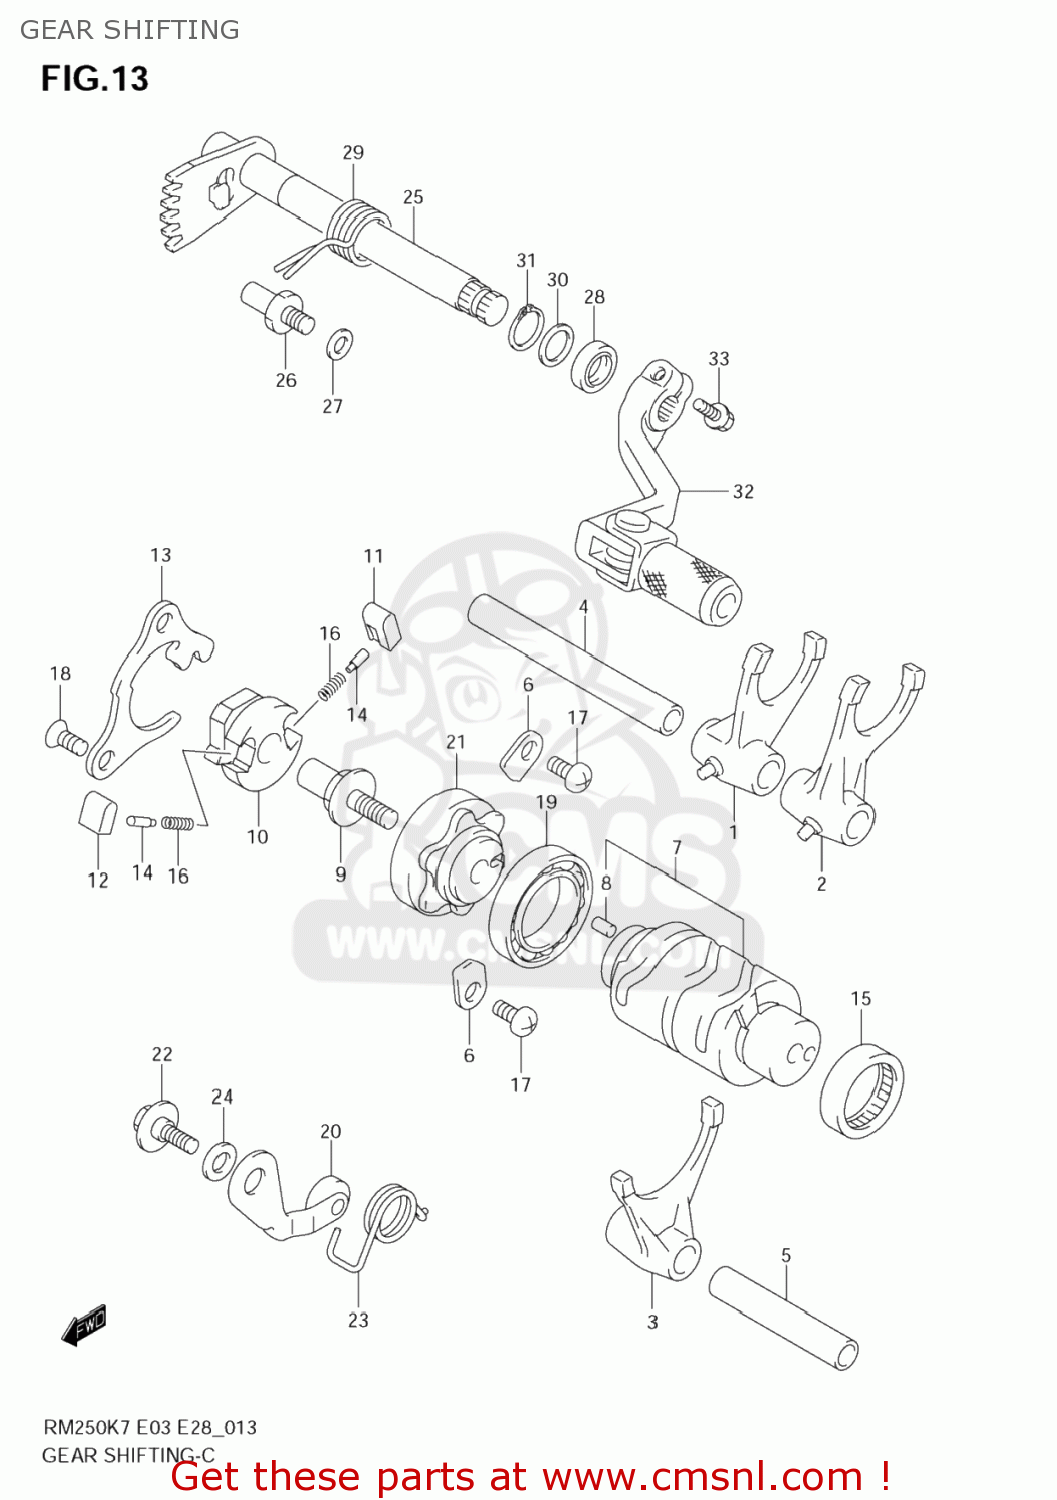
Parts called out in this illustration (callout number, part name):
1	FORK,GEAR SHIFT NO.1
2	FORK,GEAR SHIFT NO.2
3	FORK,GEAR SHIFT NO.3
4	SHAFT,GEAR SHIFT FORK(L:95)
5	SHAFT,GEAR SHIFT FORK(L:60)
6	RETAINER
7	CAM,GEAR SHIFT
8	PIN
9	PIN,GEAR SHIFT CAM
10	GEAR,GEAR SHIFT CAM DRIVEN
11	PAWL,GEAR SHIFT NO.1
12	PAWL,GEAR SHIFT NO.2
13	LIFTER,GEAR SHIFT PAWL
14	PIN
15	BEARING(25X32X12)
16	SPRING
17	BOLT(6X12)
18	SCREW(6X12)
19	BEARING
20	STOPPER,SHIFT CAM
21	PLATE,SHIFT CAM STOPPER
22	BOLT(6X14.3)
23	SPRING,SHIFT CAM STOPPER
24	WASHER
25	SHAFT,GEAR SHIFT
26	STOPPER,GEAR SHIFT ARM
27	SHIM(8.8X14X1)
28	SEAL,OIL(14X22X6)
29	SPRING
30	SHIM(14X20X1)
31	CIRCLIP
32	LEVER ASSY,GEAR SHIFT
33	BOLT
